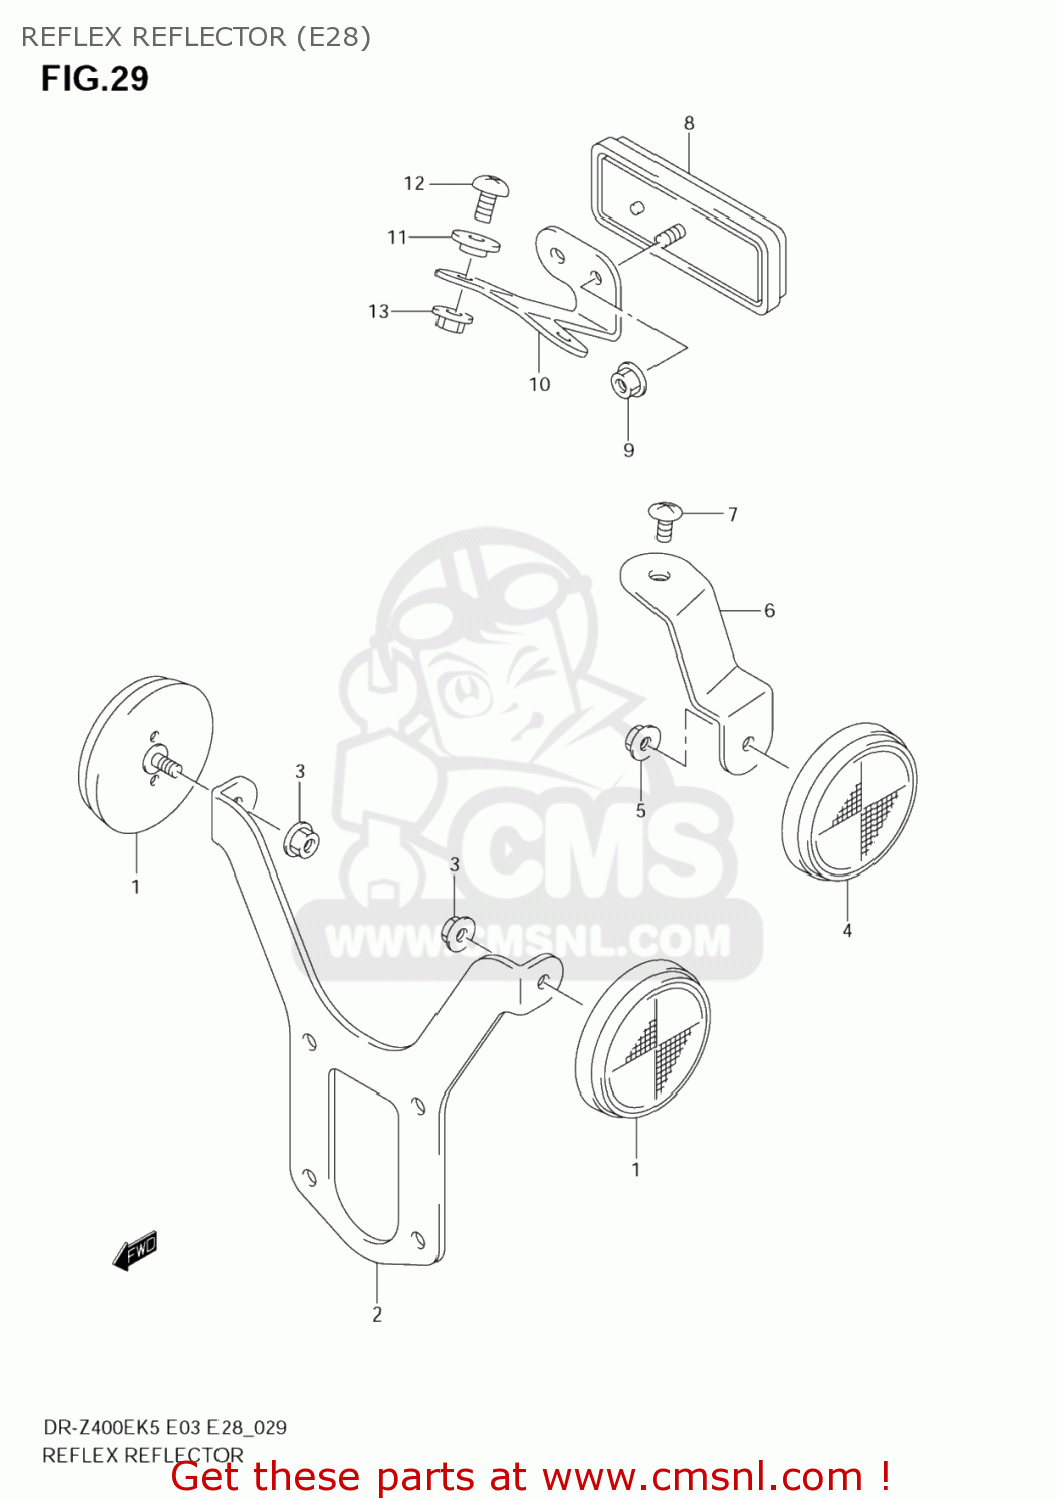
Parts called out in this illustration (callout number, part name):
1	REFLECTOR,REFLEX FR
2	BRACKET,FR SIDE RR
3	NUT
4	REFLECTOR ASSY,RR SIDE
5	NUT
6	BRACKET,RR SIDE RR,R
7	SCREW 6X12
8	REFLECTOR ASSEMBLY,REAR
9	NUT
10	BRACKET,RR RR
11	WASHER(5.5X16X1.2)
12	SCREW 5X12
13	NUT
